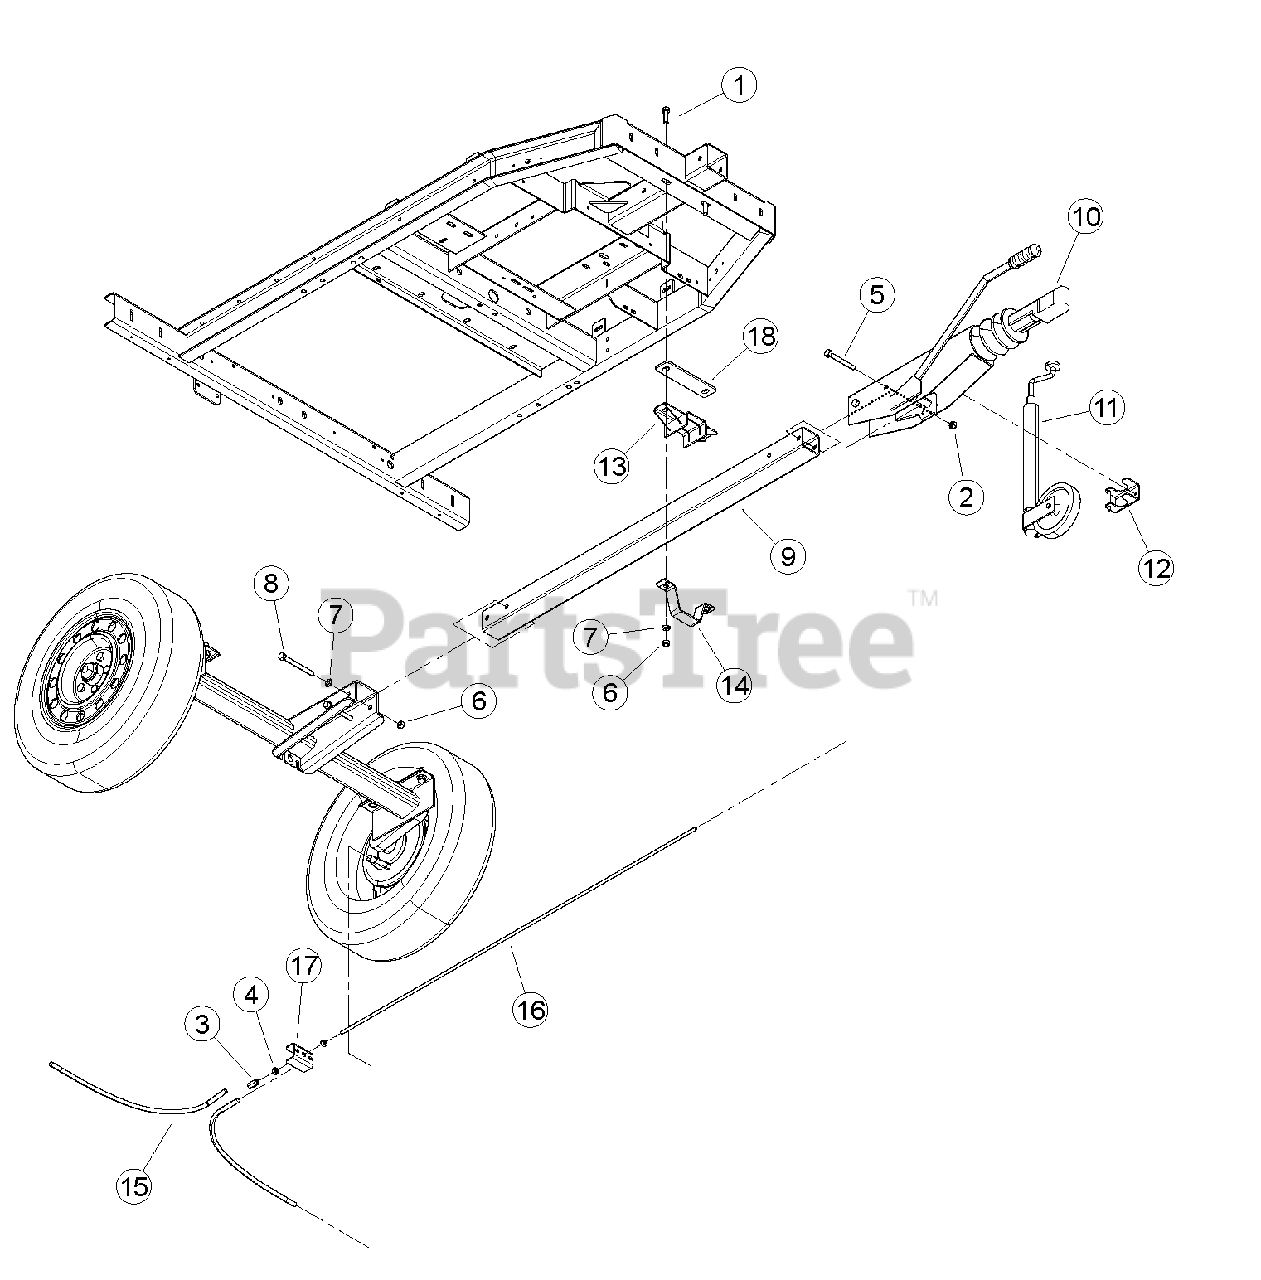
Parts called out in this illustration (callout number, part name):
1	BOLT, M12 X 1.75 X 40 GR8.8 HCPS
2	NUT, M12 X 1.75 HEX NYLOCK TYPE NEY ZP
3	BOLT, 12MM LUG FOR WHEELS
4	NUT, SPHERICAL M10 X 35MM
5	NUT, M10 HEX
6	BOLT, M12 X 100 CLASS 10.9
7	NUT, M12 HEX
8	WASHER, M12 FLAT
9	BOLT, M12 X 120 CLASS 10.9
10	DRAWBAR, 70MM X 70MM
11	COUPLER, 50MM W/ BRAKE HANDLE
12	JACK, JOCKEY WHEEL
13	CLAMP, JOCKEY WHEEL
14	MOUNT, FRONT DRAWBAR
15	CLAMP, FRONT DRAWBAR
16	CABLE, AXLE BRAKES SHORT
17	ROD, BRAKE CONTROL
18	BRACKET, BALANCE BAR
19	PLATE, DRAWBAR MOUNT
